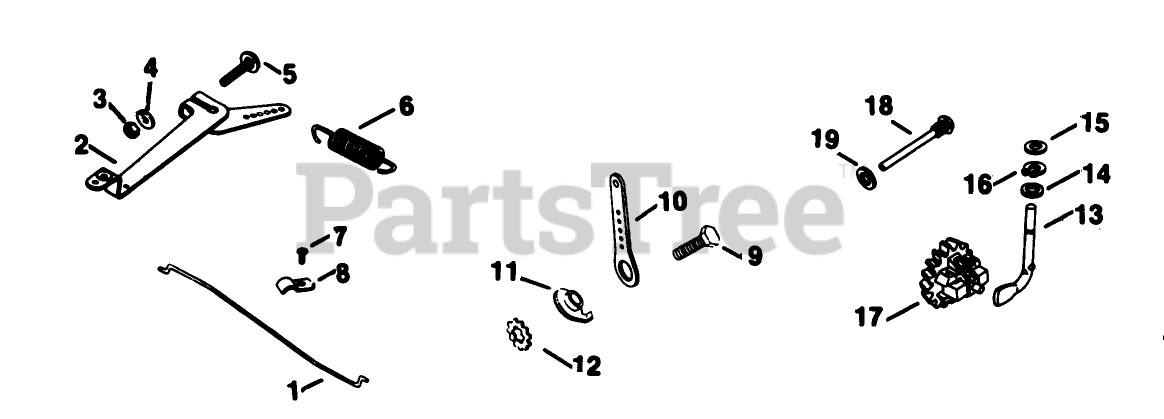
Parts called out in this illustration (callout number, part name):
1	Link-Govenor
2	Arm-Governor
4	Washer
5	Screw-Round Hd.
6	Spring-Governor
7	Screw
8	Clip
9	Screw-HH
10	Lever-Speed Control
11	Stop-Govenor
12	Washer-Lock
13	Shaft-Govenor
14	Washer
15	Washer
16	Retainer-Governor
17	Governor Gear
18	Pin-GovemorStop
19	Washer
